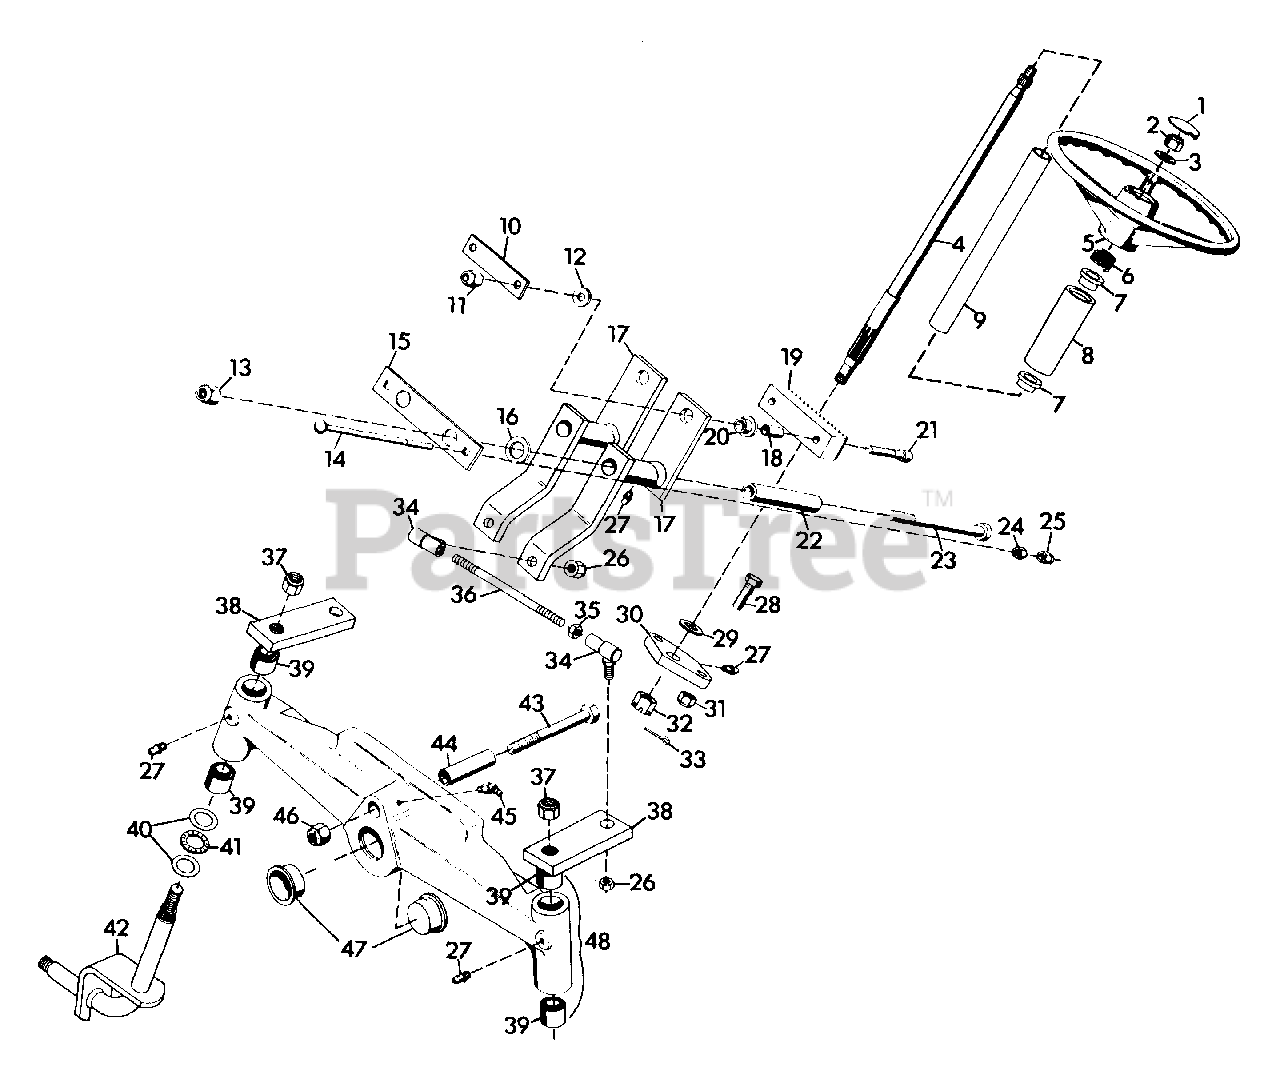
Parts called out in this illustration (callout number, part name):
1	CAP, STEERING WHEEL
2	NUT, JAM 5/8-11 HEX
3	WASHER, FLAT .656X1.312X.095
4	SHAFT, STEERING
5	WHEEL, STEERING 8122
5	WHEEL, STEERING 8123 AND 8163-B
6	SPRING, COMPRESSION 1X.80X36 LB/IN
7	BUSHING, NYLON .760X1.000X.600 FLANGE
8	BUSHING, STEERING WHEEL
9	TUBE, PLASTIC 1.0 I.D.
10	STRAP, RACK AND PINION
11	NUT, LOCK 3/8-16
12	WASHER, FLAT .375X1.125X.065
13	NUT, LOCK 1/2-13
14	BOLT, 5/16-18X5.5 RD HD SQ NK
15	PLATE, ADJUSTMENT
16	RACE, BEARING THRUST .752X1.240X.095
17	WELDMENT, STEERING
18	BUSHING, .391X.622X.670
19	GEAR, RACK
20	BEARING, FLANGE(P/M BRONZE)
21	SCREW, CAP 3/8-16X2.0 HEX SOCKET HD
22	SLEEVE, PIVOT
23	BOLT, HEX 1/2-13X6.0
24	NUT, HEX 5/16-18
25	NUT, LOCK 5/16-18
26	NUT, LOCK 3/8-24
27	FITTING, LUBE 1/4-28
28	BOLT, HEX 7/16-14X1.5
29	RACE, THRUST
30	SUPPORT, STEERING SHAFT
31	NUT, LOCK 7/16-14
32	NUT, HEX 1/2-13 SLOTTED
33	PIN, COTTER .09X1.00
34	BALL JOINT, STEERING
35	NUT, HEX 3/8-24
36	ROD, STEERING
37	NUT, HEX 5/8-11
38	ARM, TIE ROD AXLE
39	BUSHING, .877X1.004X1.0
40	RACE, BEARING THRUST
41	BEARING, NEEDLE THRUST
42	WELDMENT, KING PIN
43	BOLT, HEX 3/4-10X4.5
44	TUBE, AXLE PIVOT
45	FITTING, LUBE 45 DEG.
46	NUT, LOCK 3/4-10
47	CAP, FRONT AXLE
48	AXLE, STEERING
